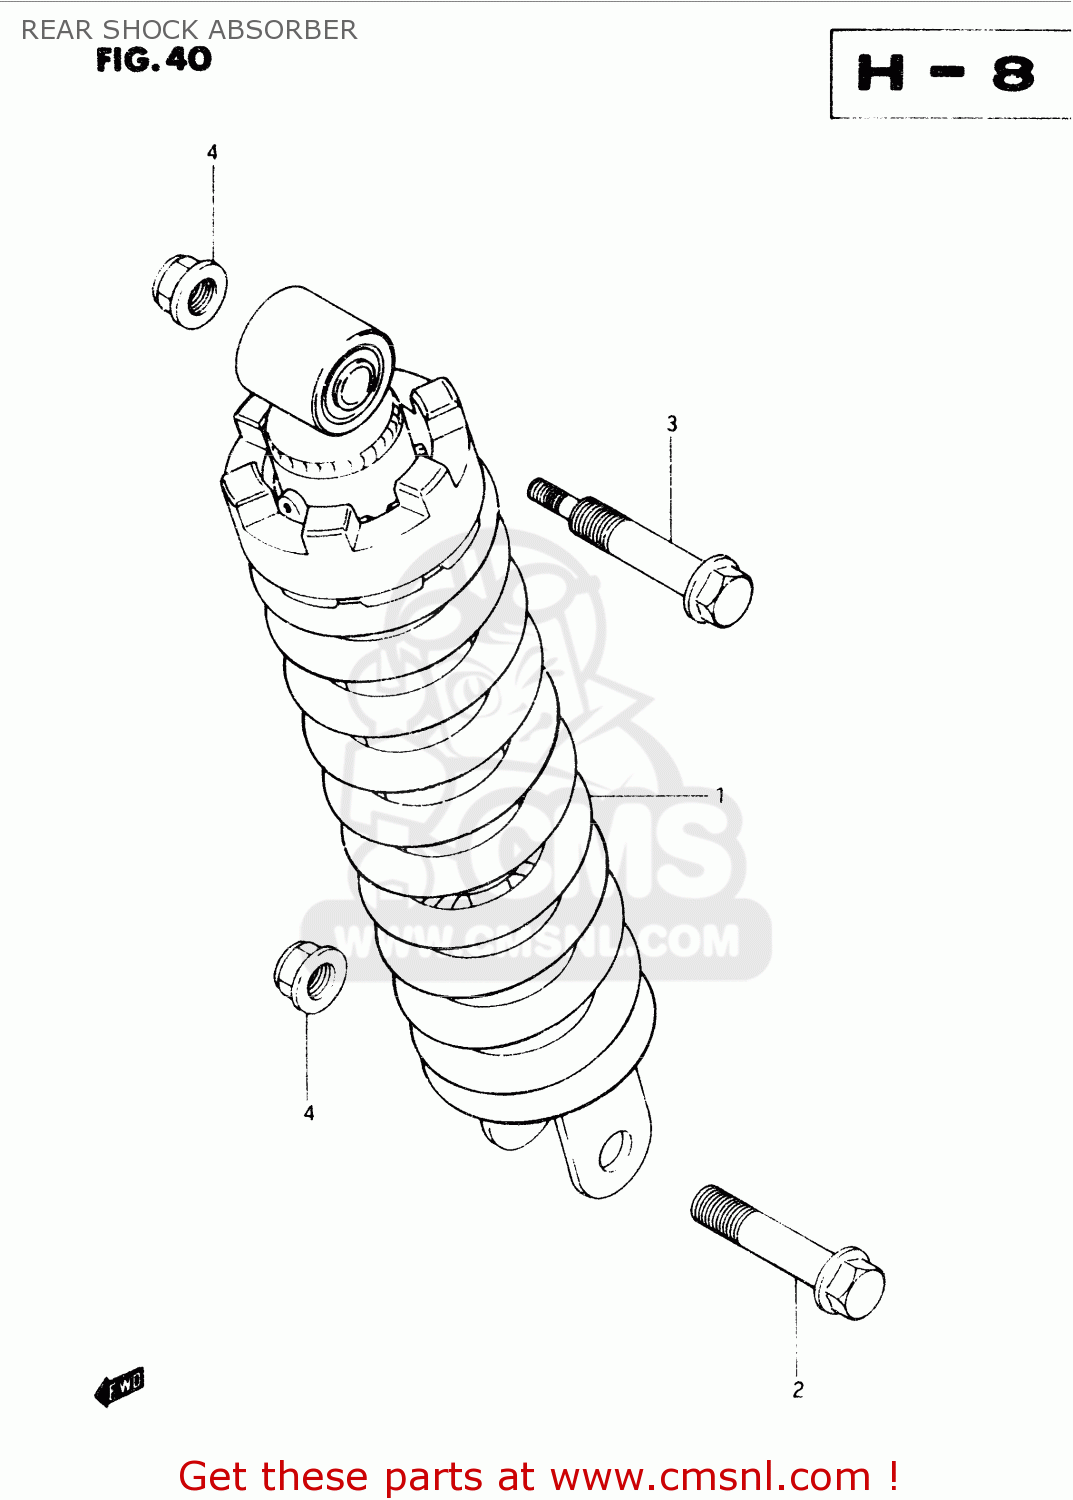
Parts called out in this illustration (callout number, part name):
1	ABSORBER ASSY, REAR SHOCK (BLACK)
2	BOLT(10X50)
3	BOLT, UPPER (L:63)
4	NUT
